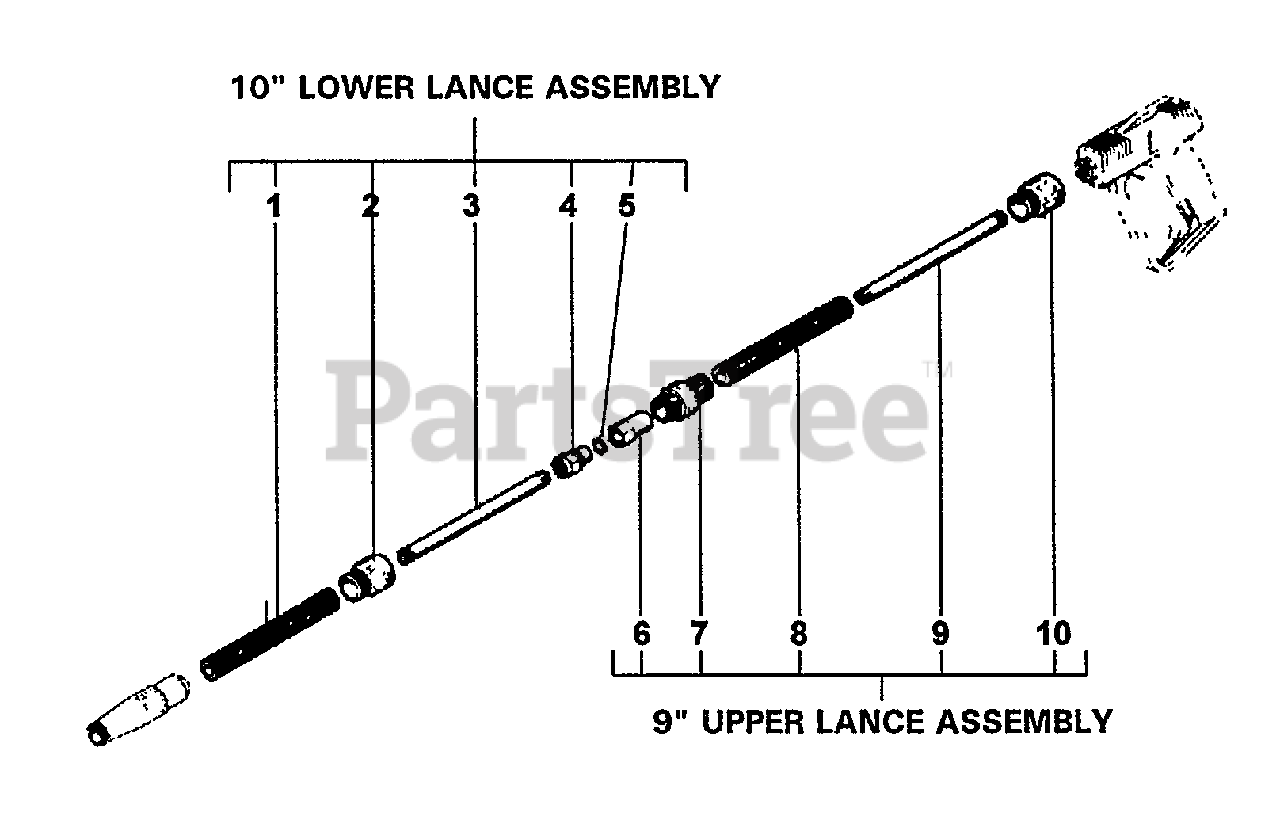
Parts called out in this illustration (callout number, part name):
1	GRIP, HANDLE
2	RINGNUT
3	TUBE
4	COUPLING - MALE
5	O-RING - .359 X .103
6	COUPLING - FEMALE
7	CONNECTOR
8	PROTECTOR, LANCE, FIX-UP
9	TUBE
10	CONNECTOR
